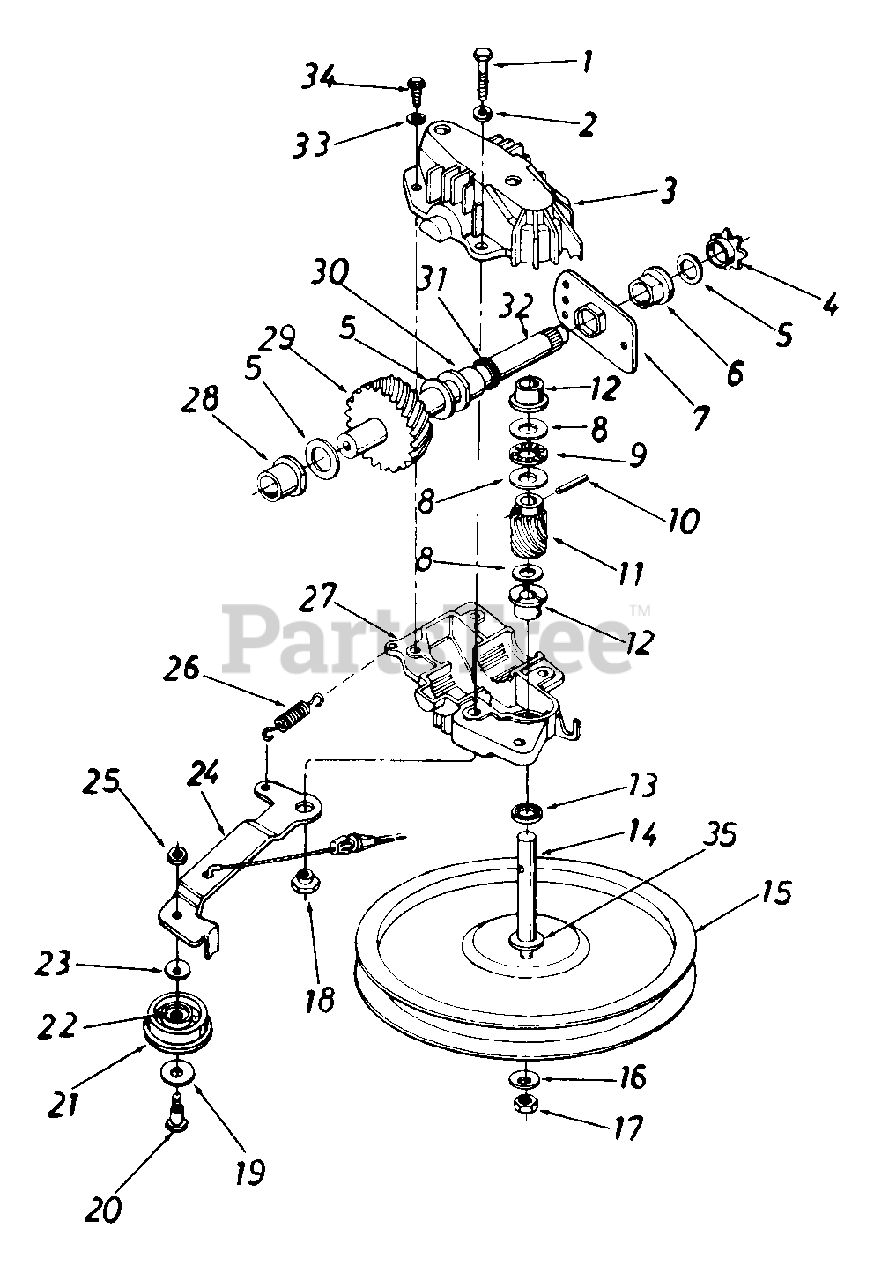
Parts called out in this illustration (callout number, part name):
1	Hex Bolt 1/4-20 x 1.25" Lg.
2	L-Wash. 1/4" I.D.
3	Upper Hsg. Half
4	#48 Sprocket 7 Tooth x 1/2 Pitch
5	Fl-Wash. 5/8" I.D. x .030
6	Hex Flange Brg. .631" I.D.
7	Hex Bearing Cup
8	Thrust Wash. .382" I.D. x .70" O.D.
9	Thrust Bearing .375" I.D. x .812" O.D.
10	Spring Pin Spir. 1/8" x .62" Heavy
11	11 Tooth Helical Gear
12	Flange Bearing
13	Oil Seal
14	Pulley-Transmission Shaft
15	Fl-Pulley 5.06" O.D.
16	Bell-Wash. .265" I.D. x 75"
17	Hex L-Nut 1/4-28 L.H. Thd.
18	Shld. Spacer .375" Dia. x . 170
19	Fl-Wash. .390" I.D. x 1.0"
20	Shld. Bolt .375" Dia. x .40"
21	Fl-Idler Plastic 1.50" Dia.
22	Needle Brg. .375" x .31
23	Bell-Wash. .265" I.D. x 75"
24	Idler Brk t. Ass y.
25	Hex Patch L-Nut 1/4-28 Thd.
26	Extension Spring 1.12" Lg.
27	Lower Hsg. Half
28	Flange Bearing .566 Dia.
29	33 Tooth Helical Gear
30	Flange Bearing .629 Dia.
31	Oil Seal .625 Dia.
32	Gear Sprocket Shaft
33	L-Wash. #10 I.D.
34	Hex B-Tap Scr. #10 x .62"
35	Hex Washer .26" x .88"
